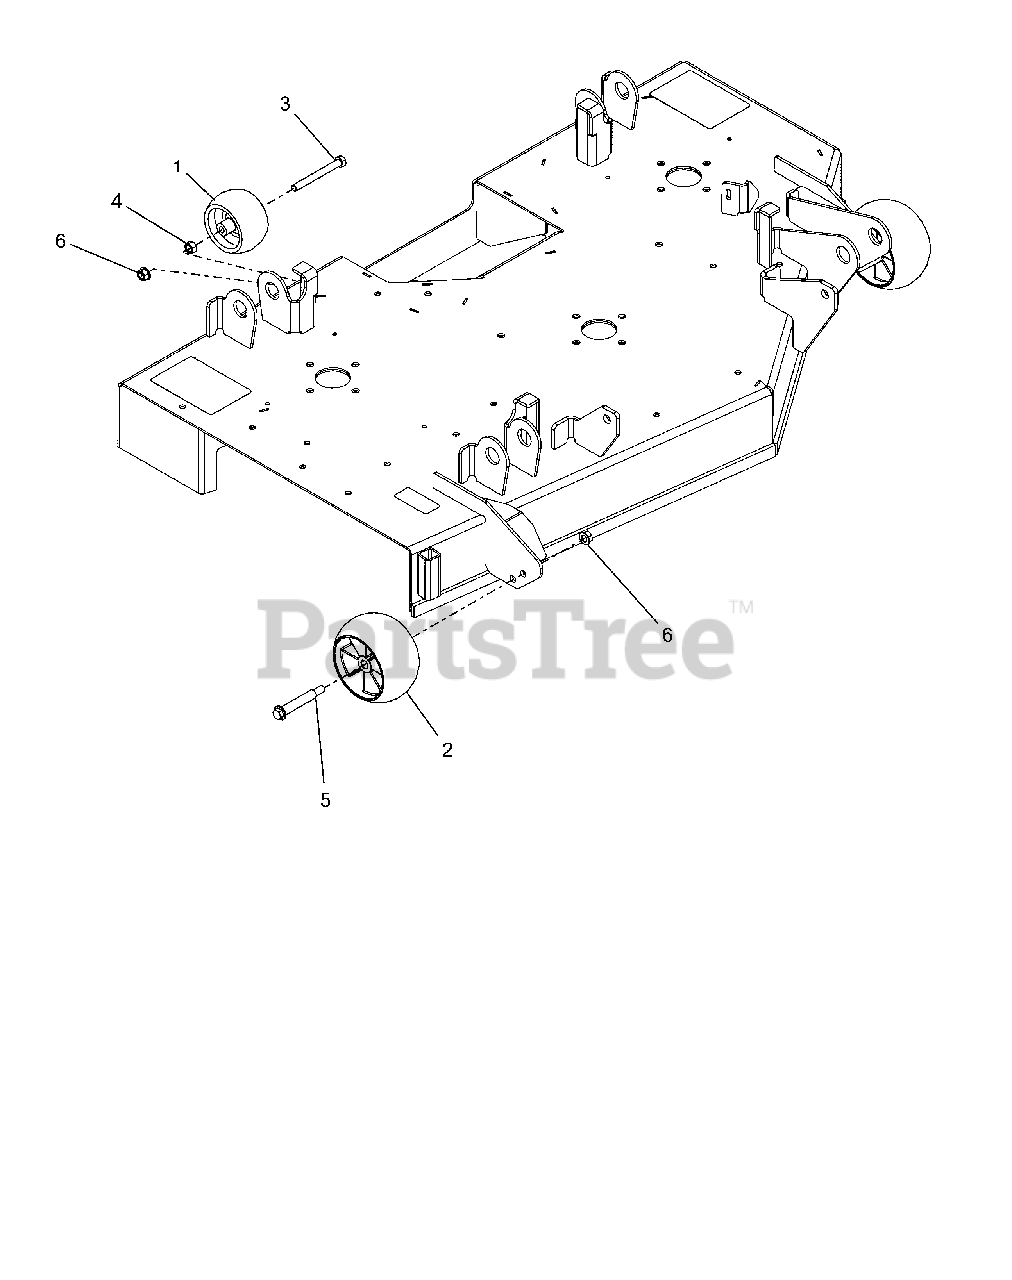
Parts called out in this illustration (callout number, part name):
2	ANTI-SCALP WHEEL - 5X OS
3	@BLT-HEX .38-16X3.50 GR5 YWZC
4	@NUT-HEX .38-16 YWZC
5	BLT-SHLDR .38-16X2.50 HWH G5
6	@NUT-LK-TOP-FLG .38-16 YWZC
